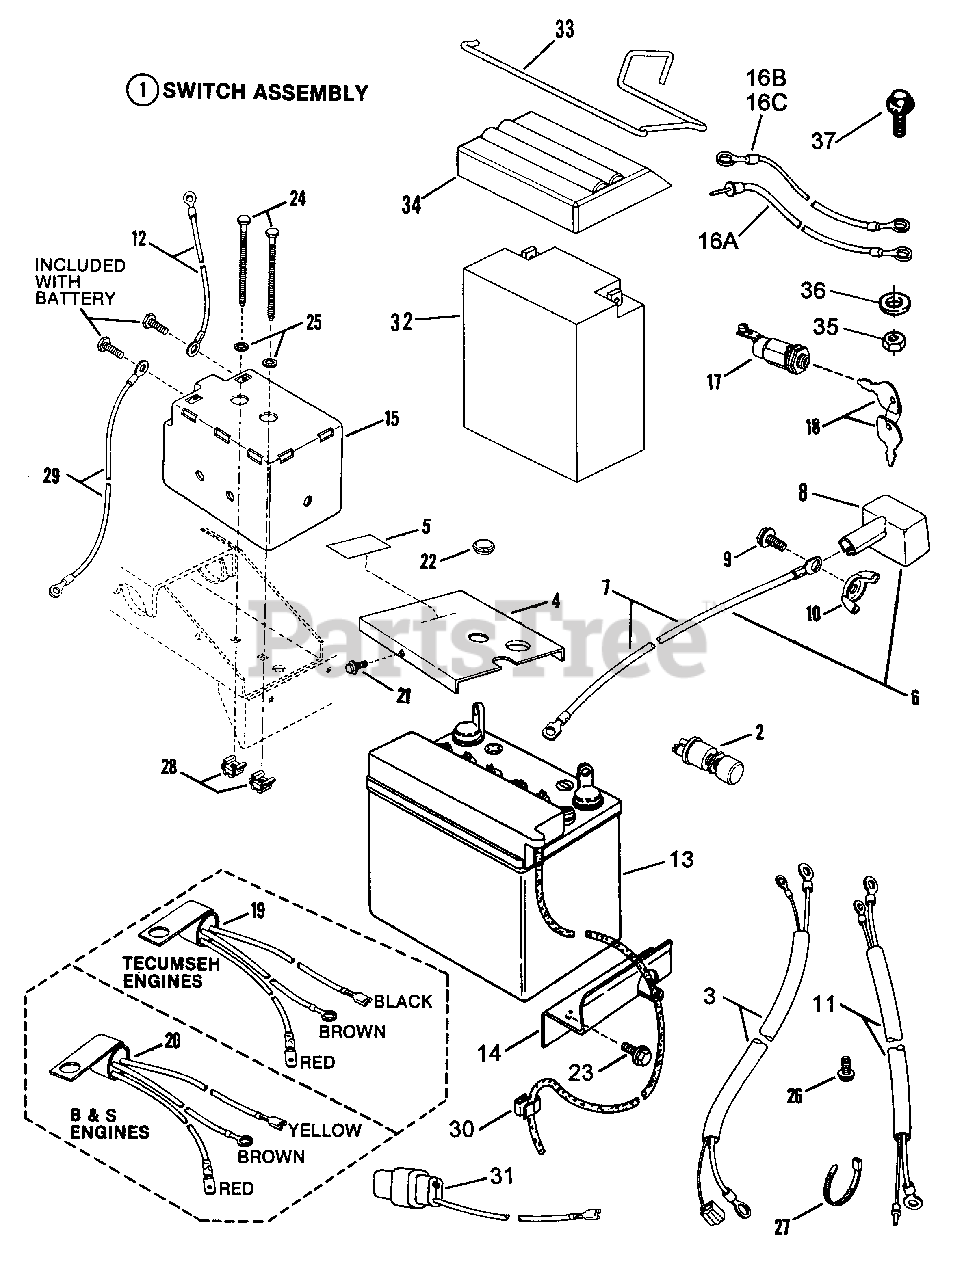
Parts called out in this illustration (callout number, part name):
1	ASSEMBLY, Switch (For Tecumseh Pushbutton Electric Start)
2	SWITCH, Pushbutton on Start
3	HARNESS, Starter Wiring (Tecumseh Electric Start)
4	PANEL, Switch (NLA, use 38240 and drill .641" switch hole)
5	DECAL, Pushbutton Electric Start Models
6	ASSEMBLY, Wire & Cover
7	CABLE, Positive Red
8	COVER, Battery Cable
9	SCREW, 5/16-18 x 3/4" Hex Head Cap
10	WING-NUT, 5/16-18
11	HARNESS, Starter Wiring (Briggs Electric Start)
12	CABLE, Positive Red (SLA Vented Battery)
13	KIT, 12V Dry Charge Battery
14	CLAMP, Battery Retaining
15	BATTERY, SLA Vented
16A	WIRE, Ground (Tecumseh with ON-OFF Switch on Front End)
16B	WIRE, Ground (Briggs with ON-OFF Switch on Front End)
16C	WIRE, Ground
17	SWITCH, Ignition
18	KEY, Switch (Pair)
19	INTERLOCK, (Tecumseh solid state)
20	INTERLOCK (Briggs)
21	SCREW, 1/4-20 x 3/8" Hex Washer Self-Tapping
23	SCREW, 5/16-18 x 5/8" Hex Washer Self-Tapping
24	SCREW, #10-32 X 3-1/2" Hex Head Machine
25	WASHER, #10 Internal Tooth
26	SCREW, 1/4-20 x 1/2" Hex Washer Self-Tapping
27	CABLE-TIE
28	RETAINER, #10-32 Nut
29	CABLE, Negative
30	HOSE CLIP
31	ADAPTER, Wire Assembly
32	BATTERY, SLA 12V/12 A.H. (1-4972 instructions)
34	COVER, Battery
35	NUT, #10-24 Hex Lock
36	WASHER, #10 External Tooth Lock
37	SCREW, #10-24 x 1/2" Hex Head Cap
